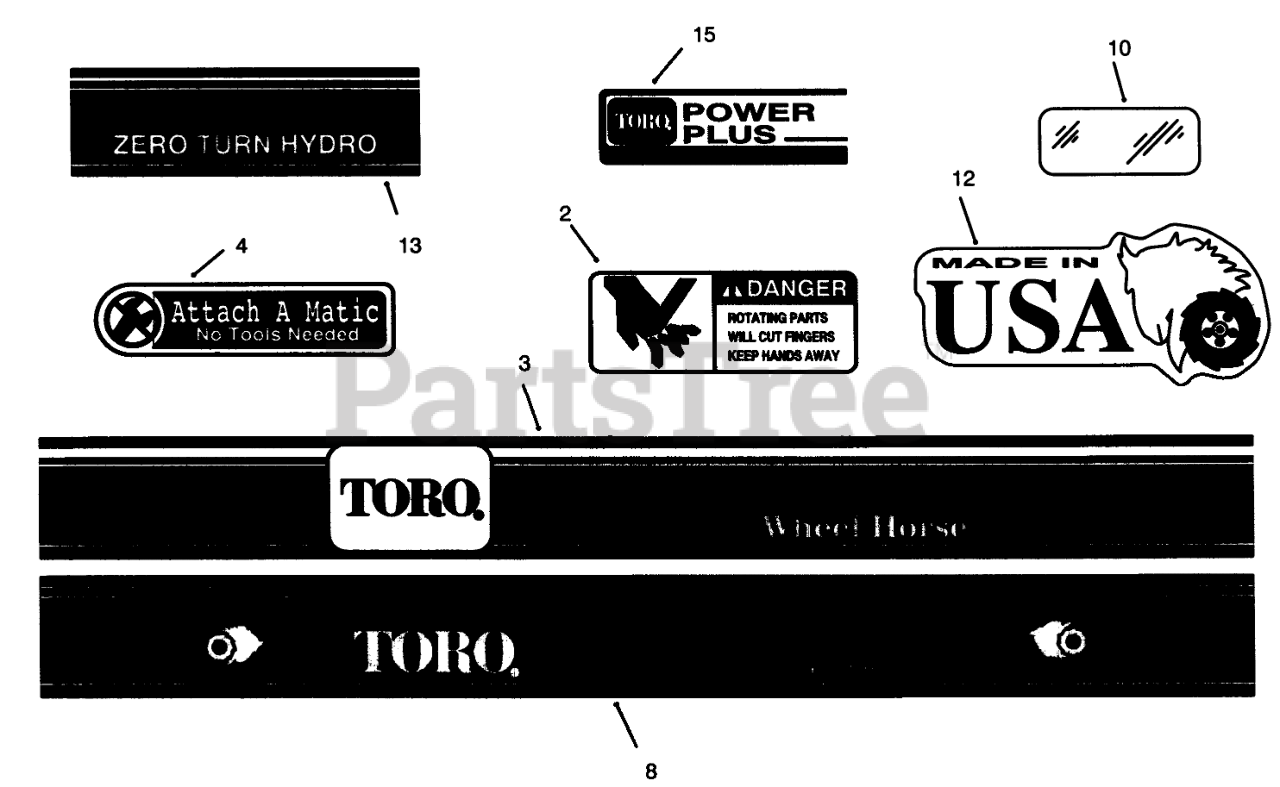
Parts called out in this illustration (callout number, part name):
2	DECAL-DANGER
3	DECAL-REAR 600
4	Decal-Attac-O-Matic
8	DECAL 616-Z
10	DECAL-OVERLAY
12	Decal-Made In USA
13	DECAL-ZERO TURN HYD
15	DECAL POWER PLUS 16
